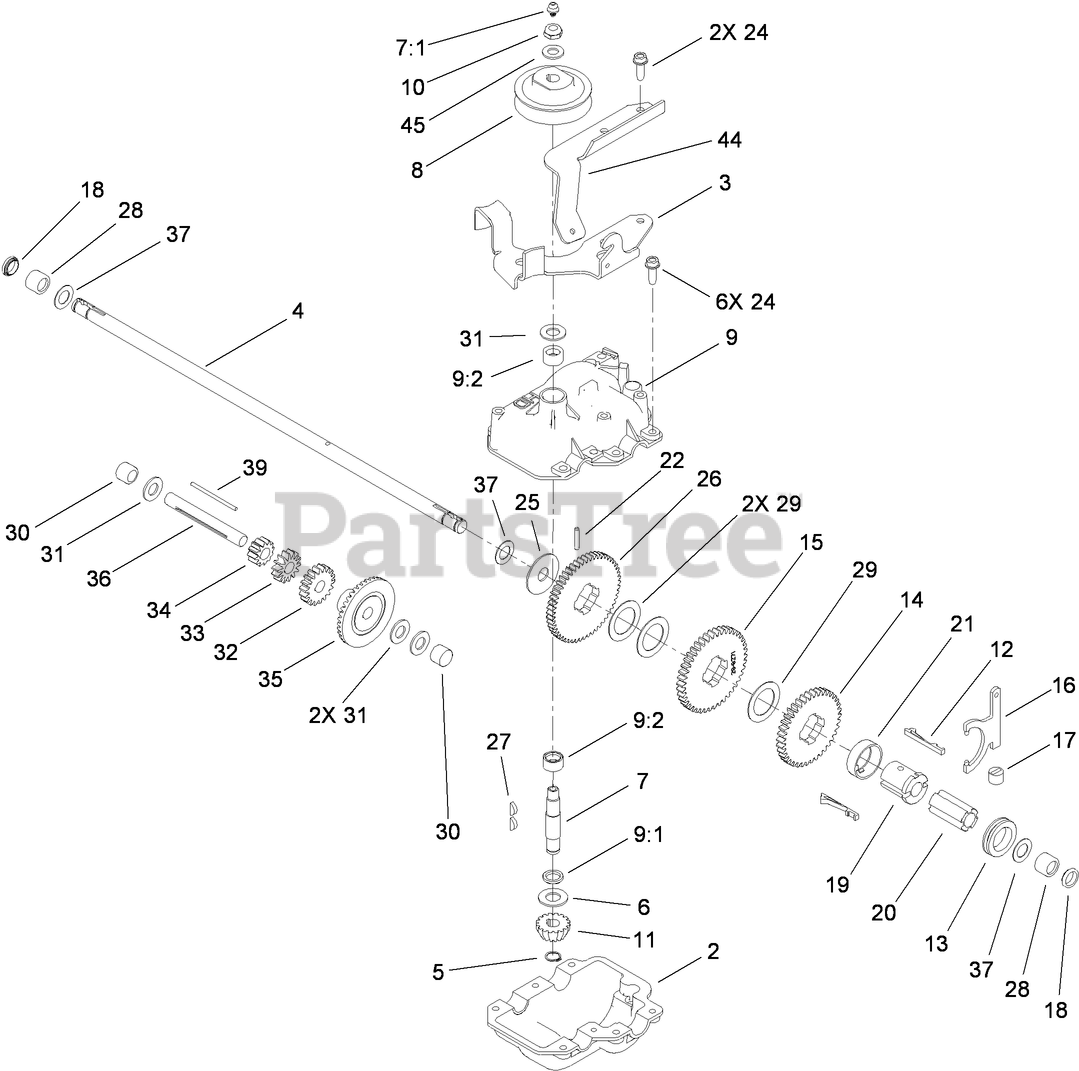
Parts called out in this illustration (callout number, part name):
2	CASE-GEAR, LOWER
3	BRACKET-GUIDE, BELT
4	SHAFT-OUTPUT
5	RING-RETAINING
6	WASHER-THRUST
7	INPUT SHAFT ASM
7:1	FITTING-GREASE, ZERK
8	PULLEY
9	UPPER GEARCASE ASM
9:2	BEARING-NEEDLE
10	NUT-HEX
11	PINION-BEVEL
12	KEY-SHIFT
13	COLLAR-SHIFT
14	GEAR-38T
15	GEAR-42T
16	YOKE-SHIFT
17	BUSHING-YOKE
18	SEAL-OIL
19	SLEEVE-GEAR
20	SLEEVE
21	RETAINER-KEY
22	PIN-GROOVE
24	SCREW-HWHTF
25	WASHER
27	KEY-WOODRUFF
28	BEARING-CAGED NEEDLE ROLLER
29	WASHER
30	BEARING-NEEDLE, CLOSED
31	WASHER-THRUST
32	GEAR-18T
33	GEAR-14T
34	GEAR-12T
35	GEAR-BEVEL
36	SHAFT-INTERMEDIATE
37	WASHER-PLAIN
44	ARM-ACTUATING, GEAR CASE
45	WASHER-FLAT
